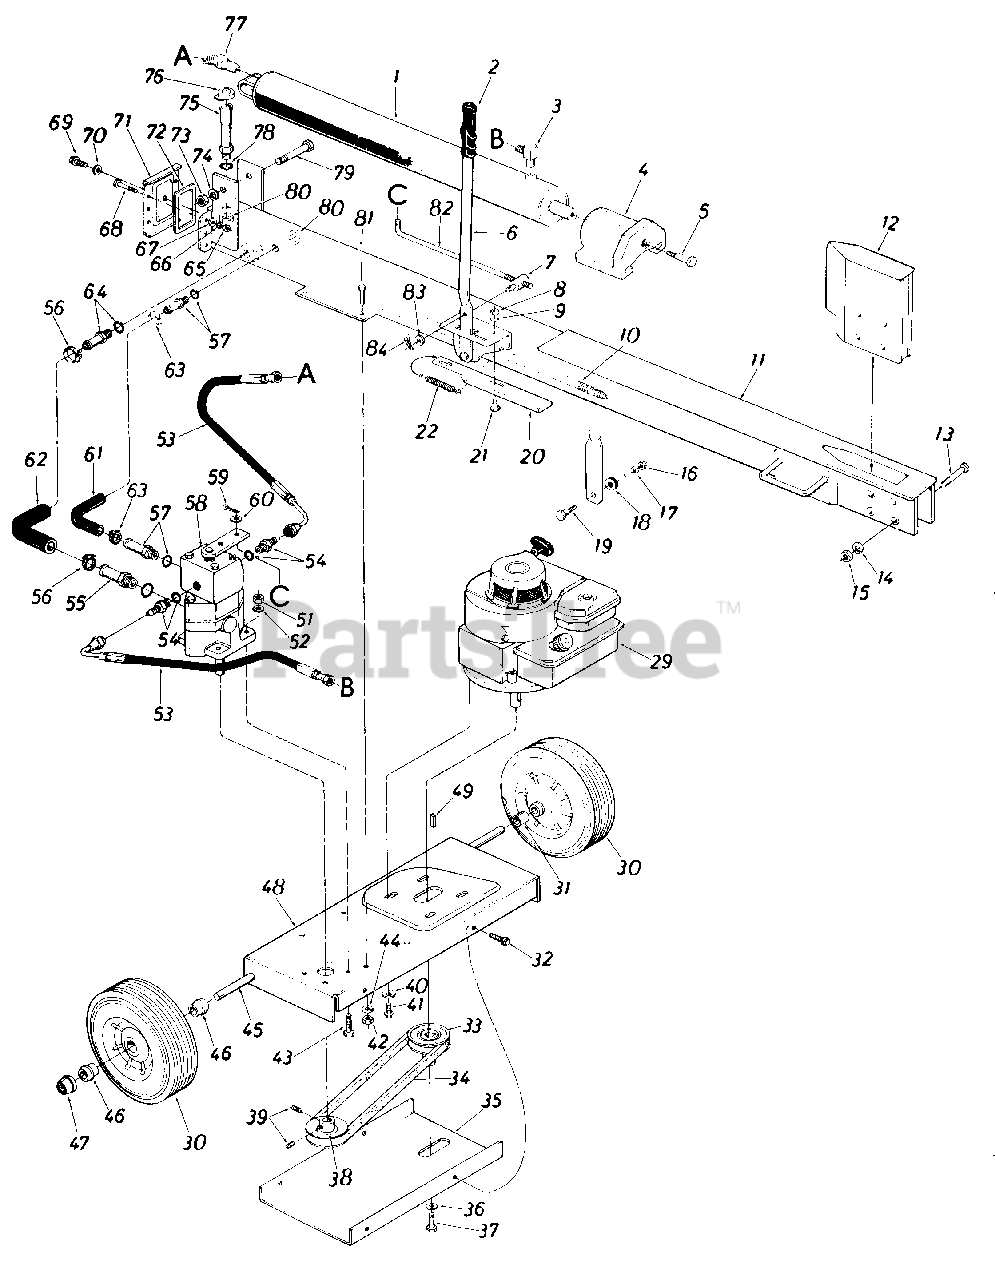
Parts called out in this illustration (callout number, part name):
1	2-1/2" CylinderAss'y. Comp
2	Grip
3	90ø Elbow Adapter
4	Pusher Plate
5	Shoulder Bolt 5/8" Dia. x .660" Lg. 1/2-13 Thd.
6	Engagement Handle
7	Adjustment Ferrule
8	Hex Nut 5/16-18 Thd.
9	L.-Wash. 5/16" I.D.
10	Strainer Tube Ass'y.
11	Oil Tank Ass'y. Comp
12	Wedge Ass y.
13	Hex Bolt 5/8-18 x 3.50" Lg.
14	L.-Wash. 5/8" I.D.
15	Hex Nut 5/8-18Thd.
16	Hex Nut 3/8-16 Thd.
17	L.-Wash. 3/8" I.D.
18	Rubber Wash.
19	Shoulder Bolt .498x .340
20	Engagement Brkt.
21	Shoulder Bolt .437" Dia. x.180" Lg.
22	Extension Spring .50" O.D. x 4.25" Lg.
29	Engine-B&S
30	Wheel Ass'y. Comp. 10.0" x 2.75
31	Sleeve .532" I.D. x 875" O.D. x .90" Lg.
32	Hex Wash. Hd. Self Tap. Scr. 1/4-20 x .50" Lg.
33	1/2" V-Pulley 7/8" I.D. x 7/8" I.D. x 3-1/4" O.D.
34	"V"-Belt (4L) 1/2" V x 30" Lg.
35	Belt Cover
36	L.-Wash . 5/16" I.D.
37	Hex Bolt 3/8-24 x 1.0" Lg.
38	1/2 (4L) "V"-Pulley 5/8" I.D. x 3-1/2" O.D.
39	Set Scr. 1/4-28x.25" Lg.
40	Bell.-Wash..40" I.D. x .88" 0. D.
41	Hex Wash. Hd. TT-Tap Scr. 3/8-16 x .87 " Lg.
42	Hex Nut 5/16-24 Thd.
43	Hex Bolt 5/16-18 x 1.00" Lg.
44	L.-Wash. 5/16" I.D." I
45	Axle Shaft 5/8" Dia. x 25.5" Lg.
46	Flange Brg. w/Flats .631" I.D.
47	Push Cap 5/8" Dia. Rod
48	Frame-Engine
49	Sq. Key 3/16" x 3/16" x 1.50" Lg.
51	Hex Nut 5/16-18 Thd.
52	L.-Wash. 5/16" I.D.
53	H igh Pressu re H ose
54	Adapter-or Boss to MJIC 9/16-18 to 7/16-20
55	Adapter 3/4" Tubing to 3/4-16 M-Boss
56	Hose Clamp 5/8" I.D.
57	Adapter 1/2" Tube 9/16-18 or M-Boss
58	Valve Ass'y.
59	Cotter Pin 3/32" Dia. x .75" Lg.
60	Fl.-Wash. 344" I.D. x .62" O.D. x .063
61	Return Hose.50" I.D.
62	Suction Hose.75" I.D.
63	Hose Clamp 1/4" I.D.
64	Adapter 1.0" Tube 1-1/16-12 "O"-Ring
65	Hex Nut 5/16-18 Thd.
66	L.-Wash. 5/16" I.D.
67	Fl.-Wash. .343" I.D. x .687" O.D. x .062
68	Hex Bolt 5/16-18 x 1.50" Lg.
69	Hex Hd. Tap Scr. 5/16"
70	Gasket
71	End Plate
72	Gasket
73	Hex Nut 3/4" Thd.
74	L.-Wash. 3/4." I.D.
75	Filler Tube Ass'y.
76	Oil Fill Cap
77	45O Male Adapter 7/16-20 MJ-1/4-18 NP
78	"O"-Ring .92" I.D. x 1.16" O.D. x .116 Dia.
79	Hex Bolt 3/4" x 4.0" Lg.
80	Hex Nut 11/16-12Thd.
81	Hex Bolt 5/1 6-24 x 1 .00" Lg. (Grade 5)
82	Engagement Rod 16.75" Lg.
83	Fl.-Wash. .344" I.D. x.62" O.D. x .063
84	Hair Pin Cotter 5/16" Dia.
